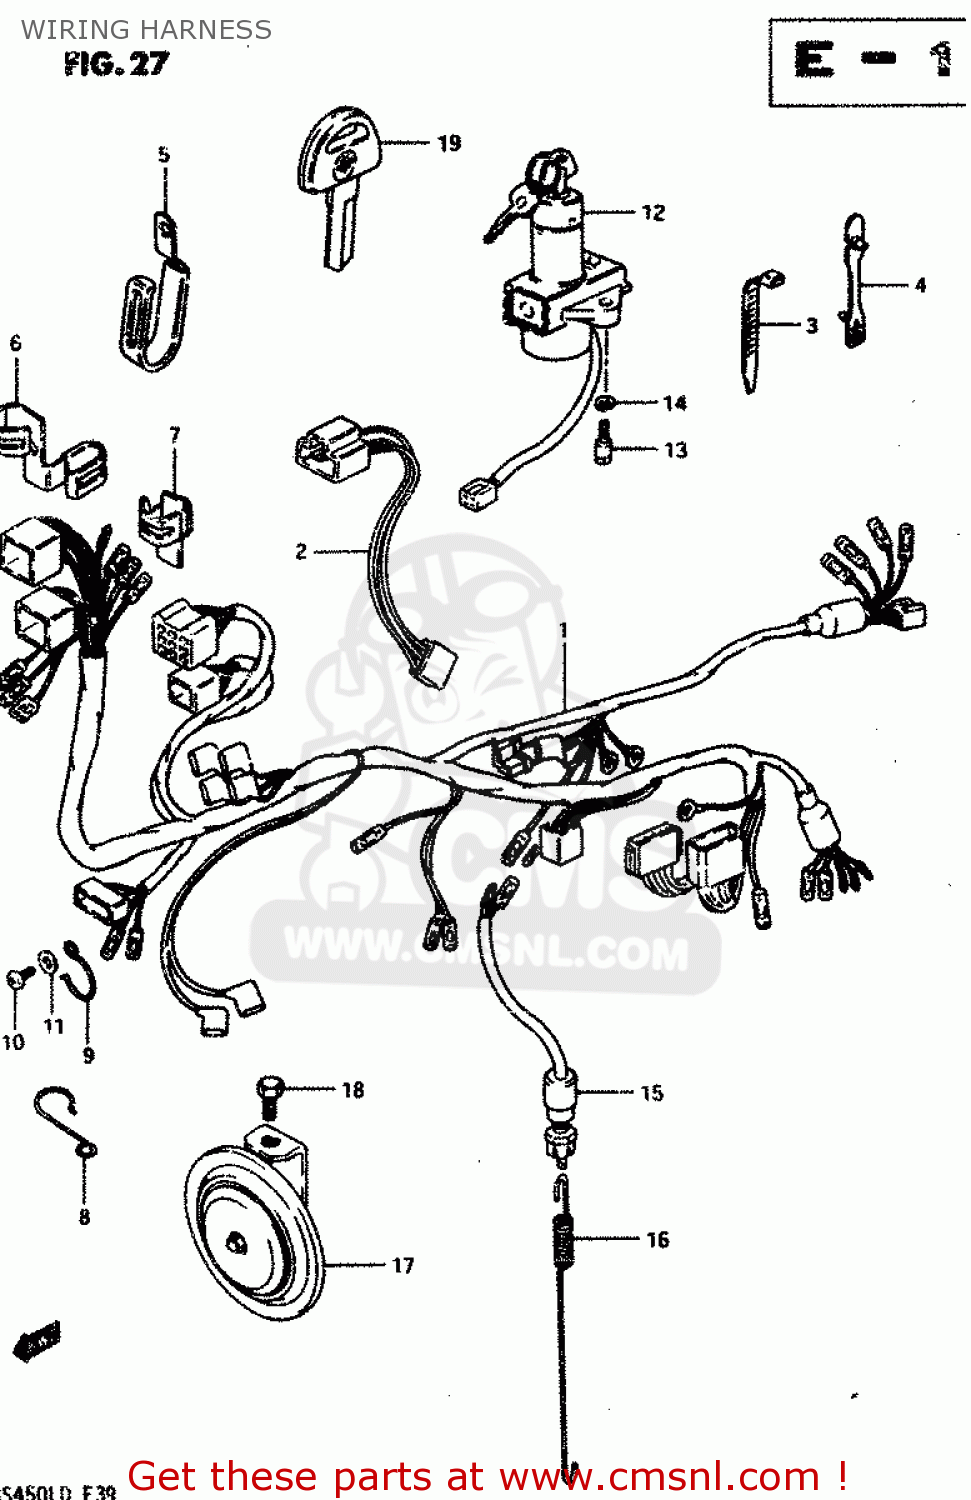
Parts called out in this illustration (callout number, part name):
1	HARNESS,WIRING
2	LEAD WIRE,HEADLAMP
3	CLAMP(L:125)
4	CLAMP,L:88
5	CLAMP,WIRING HARNESS
6	CLAMP,WIRING HARNESS
7	CLAMP,WIRING HARNESS
8	CLIP,WIRING HARNESS
9	CLIP,WIRING HARNESS
10	SCREW 6X12
11	WASHER
12	SWITCH ASSY,IGNITION
13	BOLT
14	LOCK WASHER
15	SWITCH ASSEMBLY,STOP LAMP
16	SPRING
17	HORN
18	BOLT 8X12
19	KEY,BLANK
